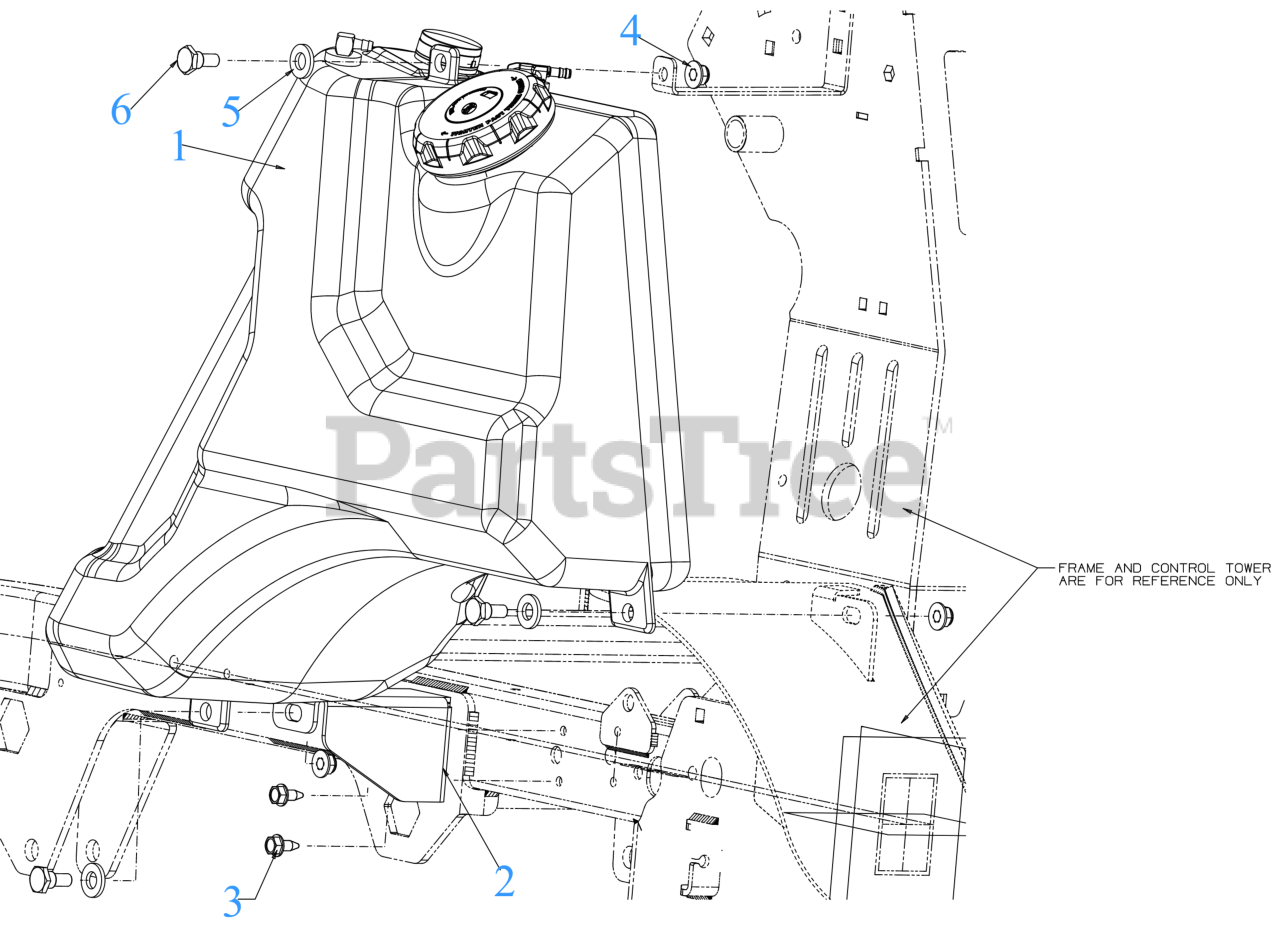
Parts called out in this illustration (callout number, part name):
1	FUEL TANK (8 Gal)
2	MOUTING BRACKET
3	SCREW 5/16-18 x .750
5	FLAT WASHER .510 x 1.000 x .125
6	SHOULDER SCREW .498 DIA x .340
